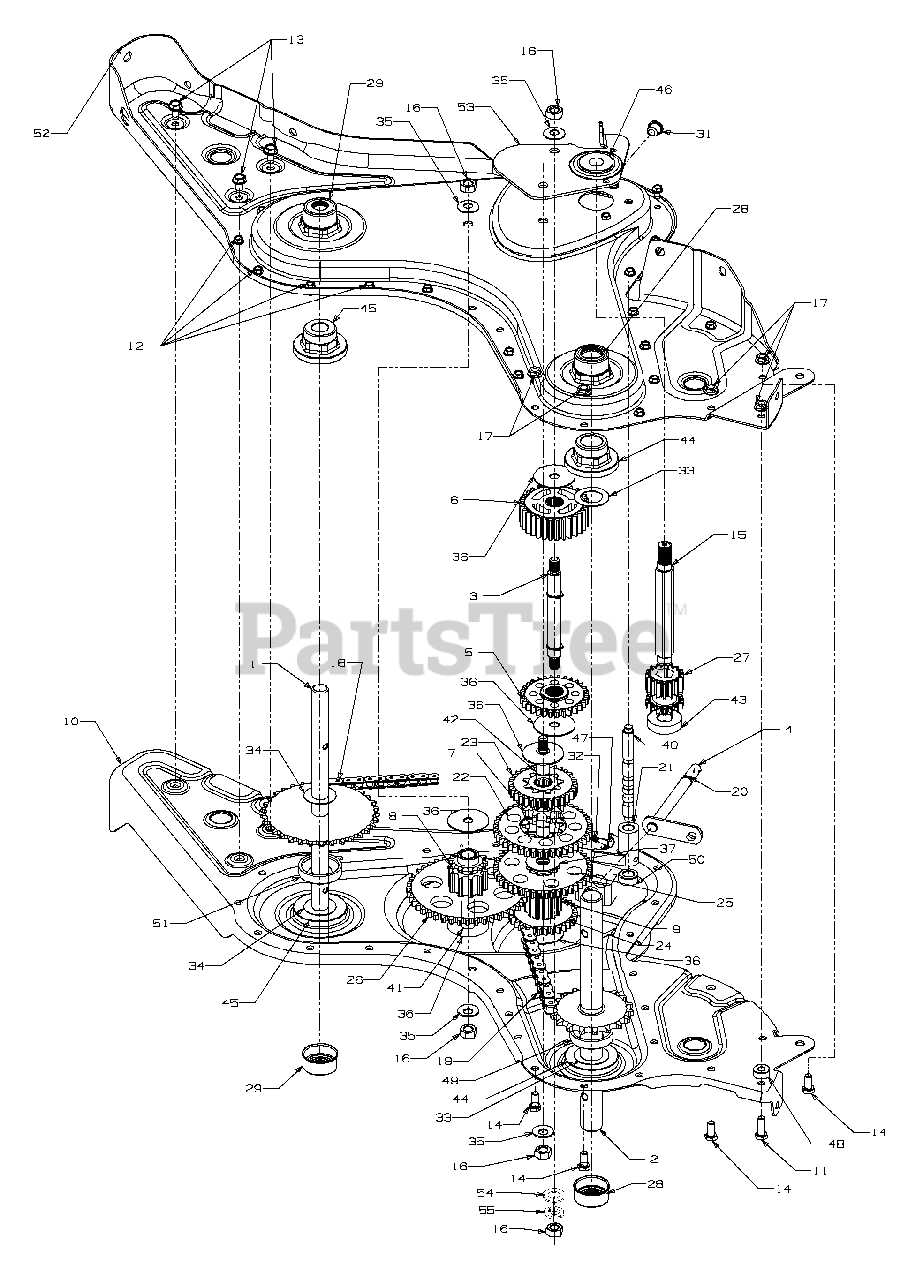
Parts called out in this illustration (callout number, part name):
1	Wheel Shaft Ass'y: 33T
2	Tine Shaft Ass'y: 18T
3	Jack Shaft Ass'y
4	Input Shaft Ass'y
5	Rev. Idler Gear Ass'y: 30T
6	Ftine Idler Gear Ass'y: 30T
7	Tine Input Sprocket Ass'y: 9T
8	Wheel Input Sprocket Ass'y: 10T
9	Gear Ass'y: 11T
10	R.H. Housing Ass'y
11	Hex Bolt 5/16-18 x 1" Lg.
12	Hex S-Tap Scr. 1/4- 20 x.5"
13	Hex S-Tap Scr. 5/16-18 x.625"
14	Hex Bolt 5/16-18 x.75"
15	Input Shaft
16	Hex Nut 7/16-20
17	Flange Nut 5/16-18
18	#420 Chain 1/2 Pitch x 50 Links
19	#50 Chain 5/8 Pitch x 54 Links
20	Snap Ring
21	Shifting Fork
22	Spur Gear 44T
23	Spur Gear 30T
24	Spur Gear 30T
25	Spur Gear 44T
26	Spur Gear 44T
27	Spur Gear 16T
28	Seal 1.0 Shaft
29	Seal.75 Shaft
31	Taper Cap Ring
32	Compression Spring.50" Lg.
33	Thrust Wash. 1.03" I.D. x 1.62"
34	Fl-Wash.76" I.D. X. 1.5" O.D.
35	Bell-Wash.45" I.D. X. 1.0"
36	Thrust Wash.445 x 1.92 x.060
37	Fl-Wash.635" I.D. x 1.59 O.D.
40	Detent Shaft 1/2" Dia.
41	Jack Shaft.625 x 2.385
42	Jack Shaft.625 x 5.0
43	Ball Bearing
44	Flange Bearing 1.0 x 2.5 x 1.38
45	Flange Bearing.75 x 2.5 x 1.38
46	Ball Bearing. 6692 x 5745 x.466
47	Detent Ball.250
48	Spacer.315
49	Spacer 1.0 I.D x 2.0 O.D. x.440
50	Spacer.505 I.D. x.88 O.D. x.440
51	Spacer.75 x 2.0 x.50
52	L.H. Chain Case Ass'y
53	Gear Positioner Bracket
54	Flat Washer,.474ID x.879OD
55	Lock Washer, 7/16
